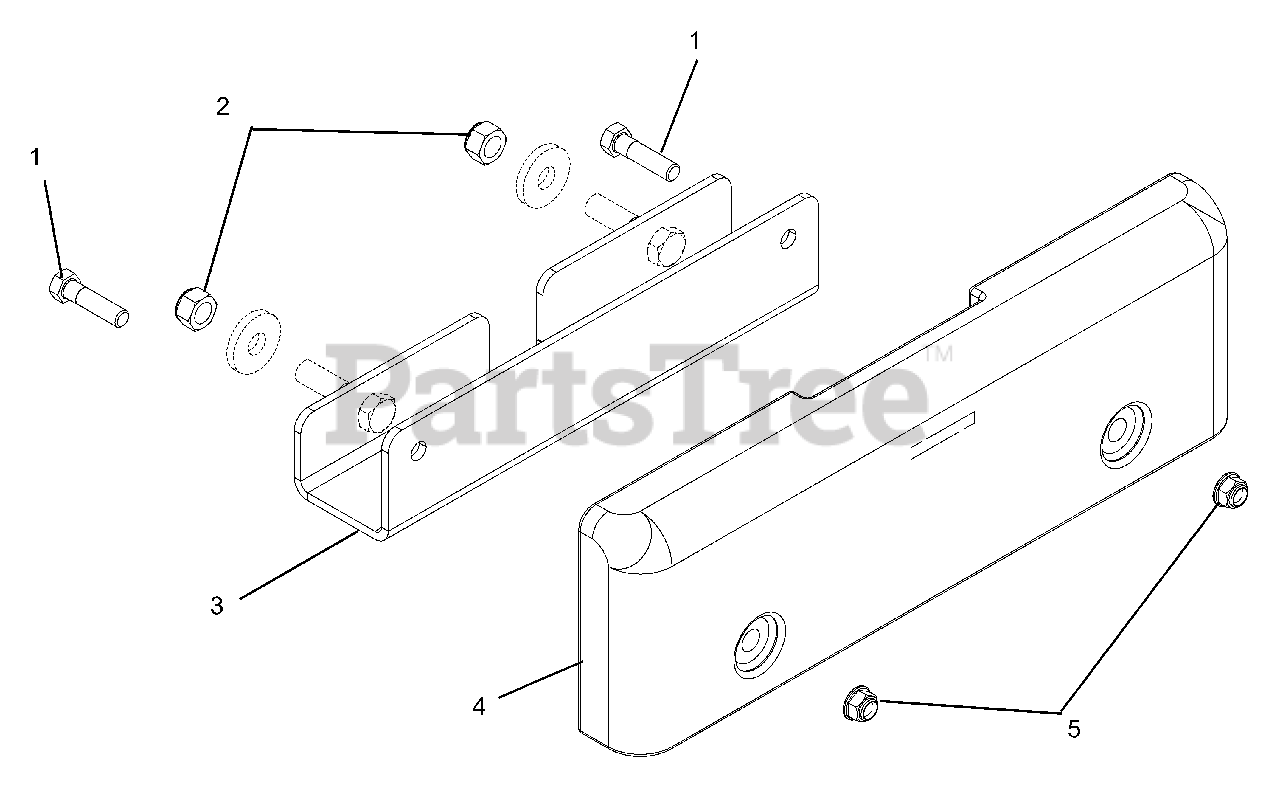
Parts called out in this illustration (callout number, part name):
1	Bolt, Hex .50-13 x 2.75 Grade 5
2	Nut, Nyloc Flange .62-11
3	Bracket, HVZ Bagger Weight
4	Counterweight
5	Nut, .50-13 Nyloc Flange
